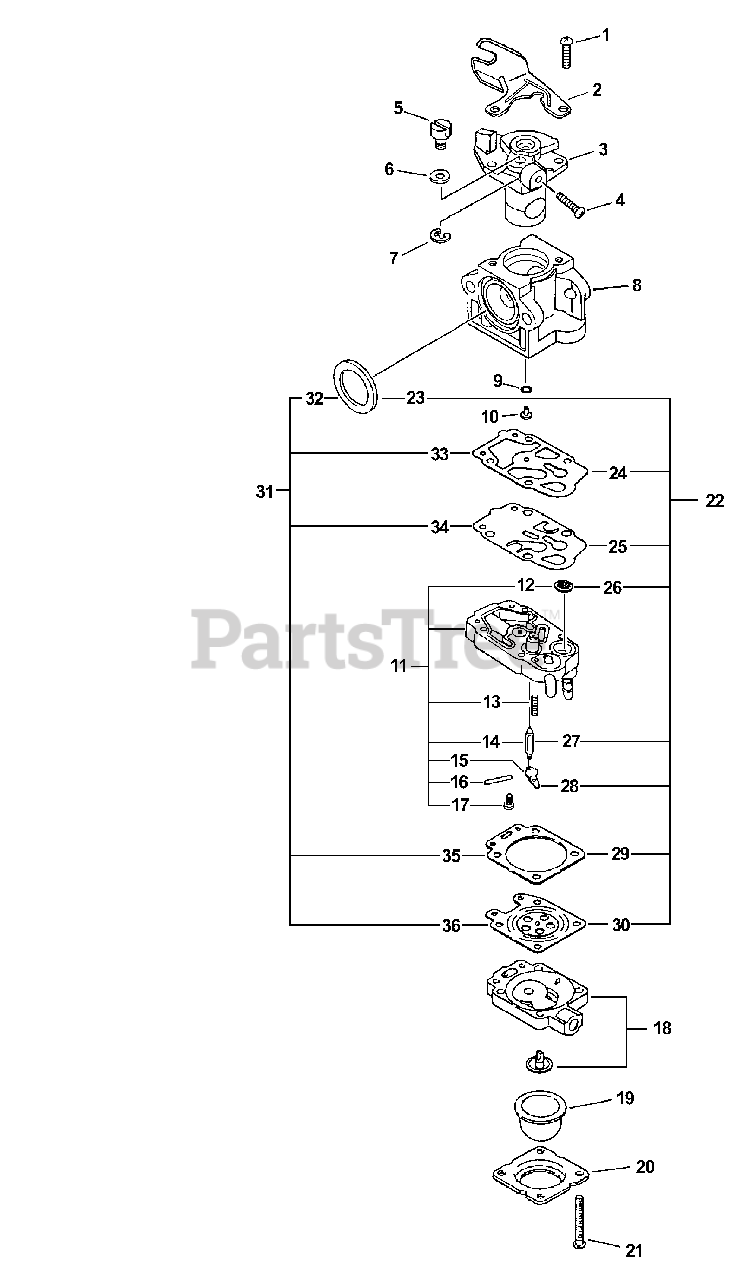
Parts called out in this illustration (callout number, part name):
2	BRACKET, THROTTLE CABLE
3	THROTTLE VALVE ASSY
8	BODY, CARBURETOR
10	JET, MAIN
11	BODY ASSY, PUMP
12	STRAINER
13	SPRING, METERING LEVER
14	VALVE, INLET NEEDLE
15	LEVER, METERING
16	PIN, METERING LEVER
18	BODY ASSY, PURGE
19	BULB, PURGE
20	RETAINER, PURGE BULB
22	REPAIR KIT, CARBURETOR
23	SEAL
24	GASKET, PUMP
25	DIAPHRAGM, PUMP
26	STRAINER
27	VALVE, INLET NEEDLE
28	LEVER, METERING
29	GASKET, METERING
30	DIAPHRAGM, METERING
31	GASKET / DIAPHRAGM KIT
32	SEAL
33	GASKET, PUMP
34	DIAPHRAGM, PUMP
35	GASKET, METERING
36	DIAPHRAGM, METERING
